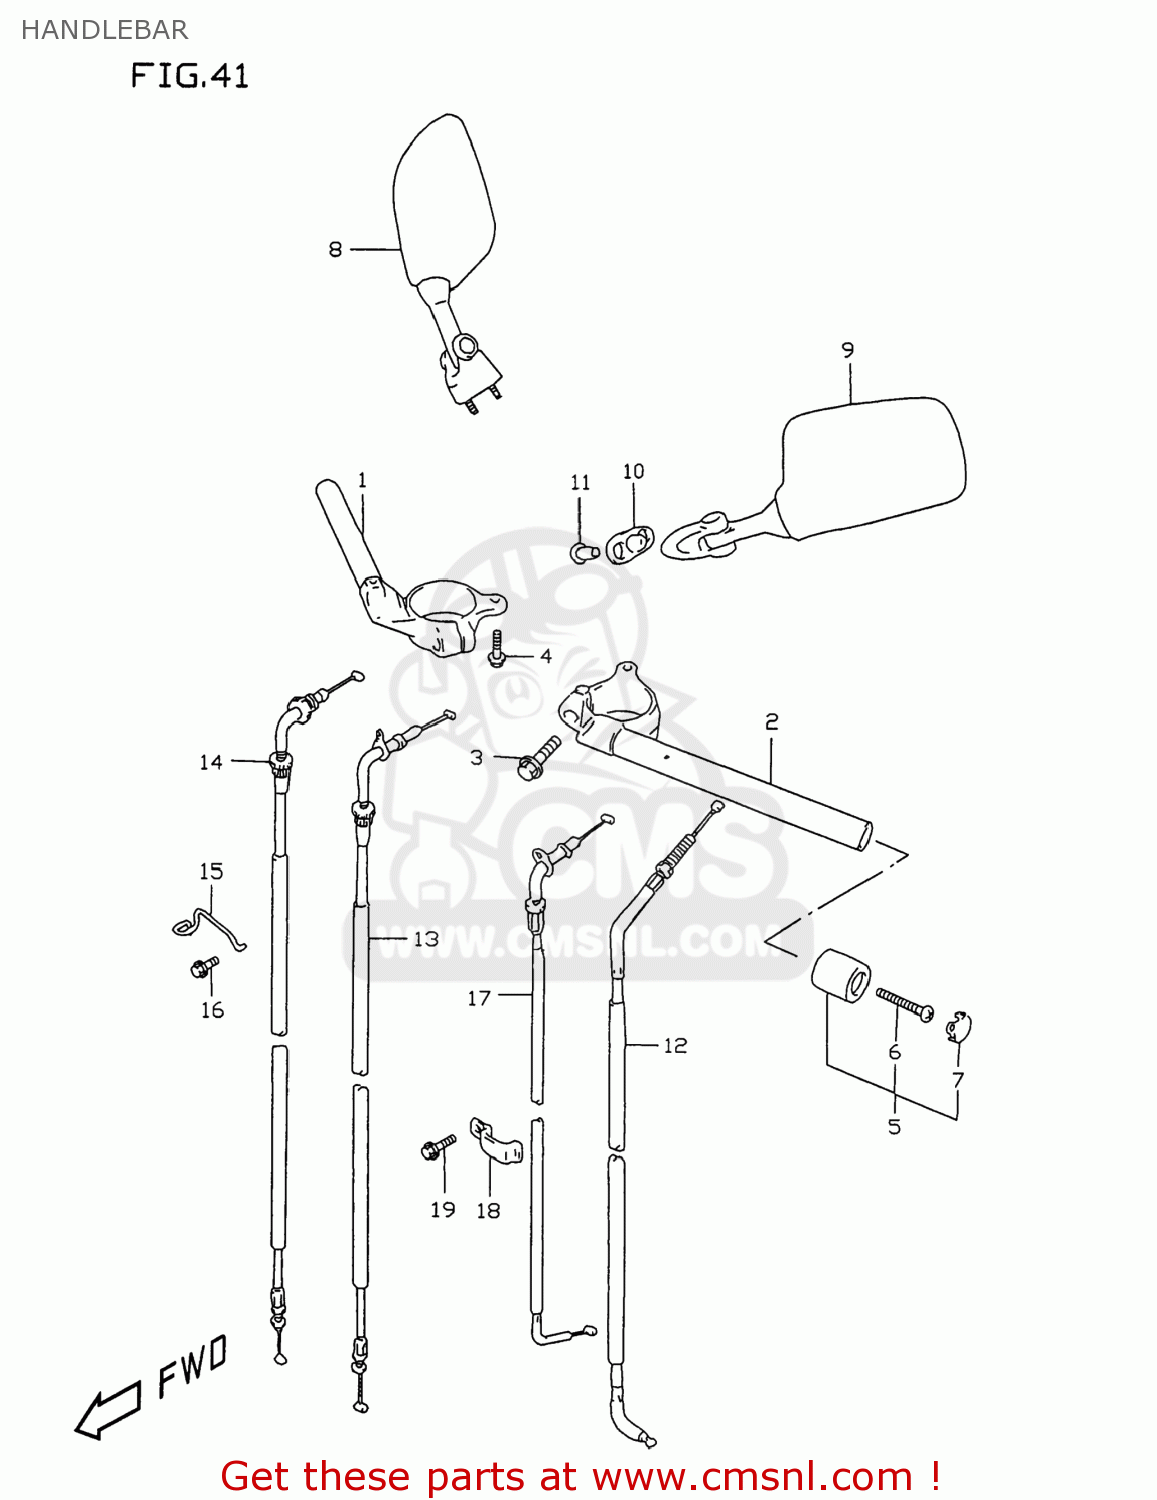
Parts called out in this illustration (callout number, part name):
1	HANDLEBAR,R
2	HANDLEBAR,L
3	BOLT
4	BOLT(8X30)
5	BALANCER SET,HANDLEBAR
6	SCREW
7	CAP,BALANCER
8	MIRROR ASSY,RR VIEW,R
9	MIRROR ASSY,RR VIEW,L
10	CUSHION,RR VIEW MIRRORR
11	NUT,RR VIEW MIRROR
12	CABLE ASSY,CLUTCH
13	CABLE ASSY,THROTTLE NO.1
14	CABLE ASSY,THROTTLE NO.2
15	GUIDE,THROTTLE CABLE
16	BOLT
17	CABLE,STARTER
18	CLAMP
19	BOLT
